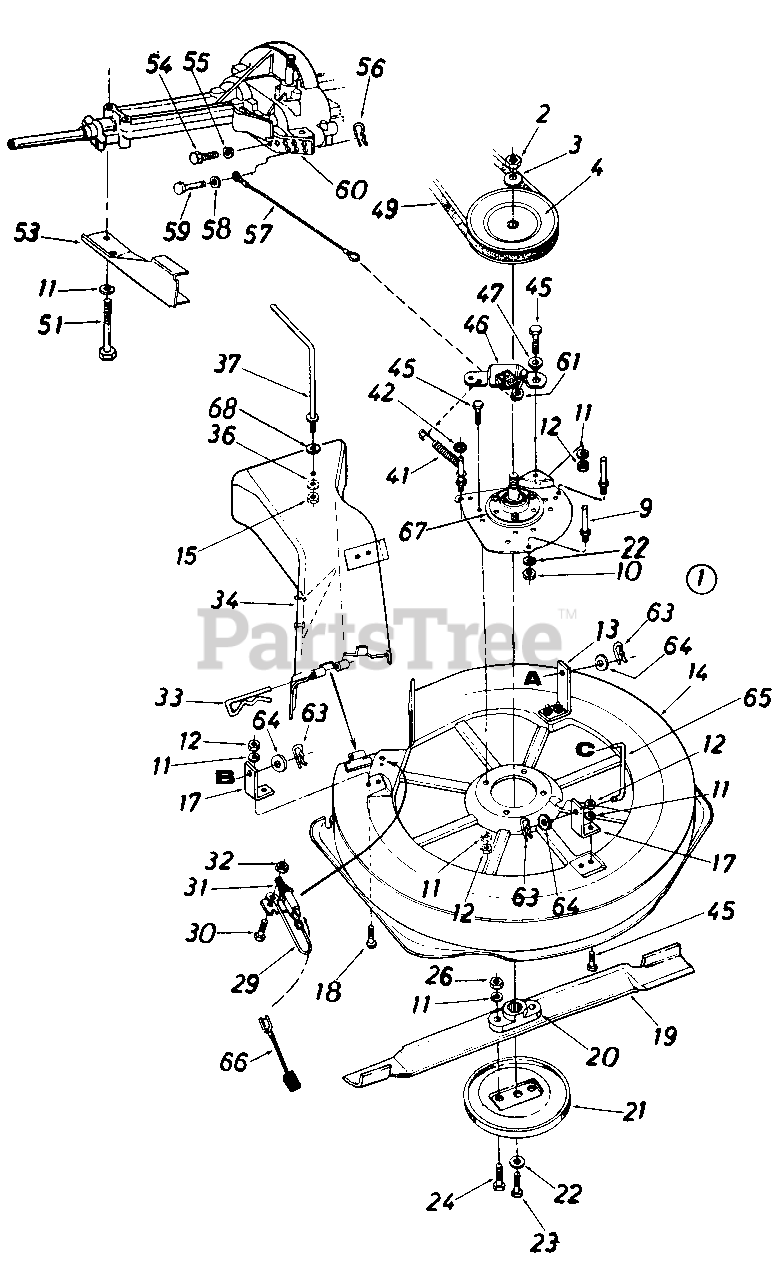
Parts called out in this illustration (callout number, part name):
1	30" R.D. Deck Ass'y. Comp.
2	Hex Jam Nut 5/8-18 Thd.
3	Bell-Wash. .630" I.D. x 1.25"
4	5/8 V-Pulley .75" I.D. x .7"
9	Stud 3/8-16 x 2.75" Lg.
10	Hex Jam Nut 3/8-16 Thd.
11	L-Wash. 5/16" I.D.
12	Hex Nut 5/16-18 Thd.
19	30n High Lift Blade
20	Blade Adapter
21	Scalp Plate
22	L-Wash. 3/8n l.D. H.D.
23	Hex Bolt 3/8-24 x 1.0
24	Hex Bolt 5/16-24 x 1.0n Lg.
26	Hex Nut 5/16-24 Thd.
29	Electrical Wire
30	Hex Bolt 1/4-20 x .50" Lg.
31	Safety Switch
32	Hex Nut 1/4-20 Thd.
33	Internal Cotter Pin
34	R.D. Chute Deflector
36	L-Wash. .32" I.D. x .62" O.D.
37	90ø Rod 5/16-18 Thd.
41	Extension Spring
42	Push Speed Nut
45	Hex Bolt 5/16-18 x .75"
46	Blade Brake Brkt. Ass'y.
47	Shoulder Spacer .500" Dia.
49	"V"-Belt 1/2 " x 52" Lg.
51	Hex Bolt 5/16-18 x 2.75"
55	L-Wash. 1/4" I.D.
56	Int. Cot. Pin 5/16" Dia.
57	Brake Cable 9.75" Lg.
58	Fl-Wash. .281" I.D. x .50"
59	Clevis Pin 1/4" Dia.
60	Lower Inside Belt Guard
61	Cap Speed Nut 1/4" Rod
63	Int. Cotter Pin 1/2" Dia.
64	Fl-Wash. .531" I.D. x .930'
65	Deck Link 3.9" Lg.
67	Blade Spindle Ass'y. Comp.
68	Fl-Wash. .344" l.D. x 1.125"
